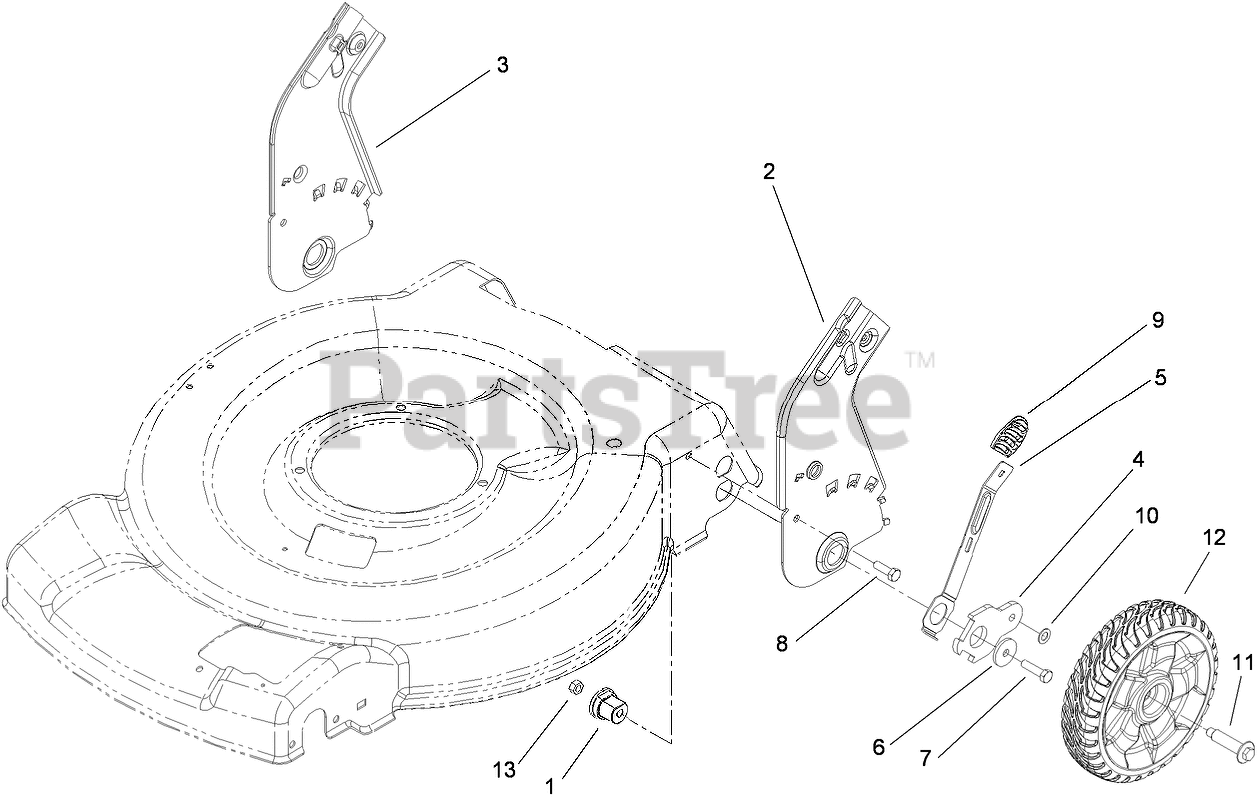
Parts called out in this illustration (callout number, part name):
1	BUSHING-MOUNT, HOC
2	PLATE-HOC, REAR (LH)
3	PLATE-HOC, REAR (RH)
4	ARM-PIVOT, REAR
5	ARM-SPRING, REAR
6	Washer-Flat
7	SCREW-HH
8	SCREW-HH
9	Knob-Lever, HOC
10	WASHER
11	BOLT-SHOULDER
12	8 inch WHEEL ASM
13	NUT-LOCK, NI
